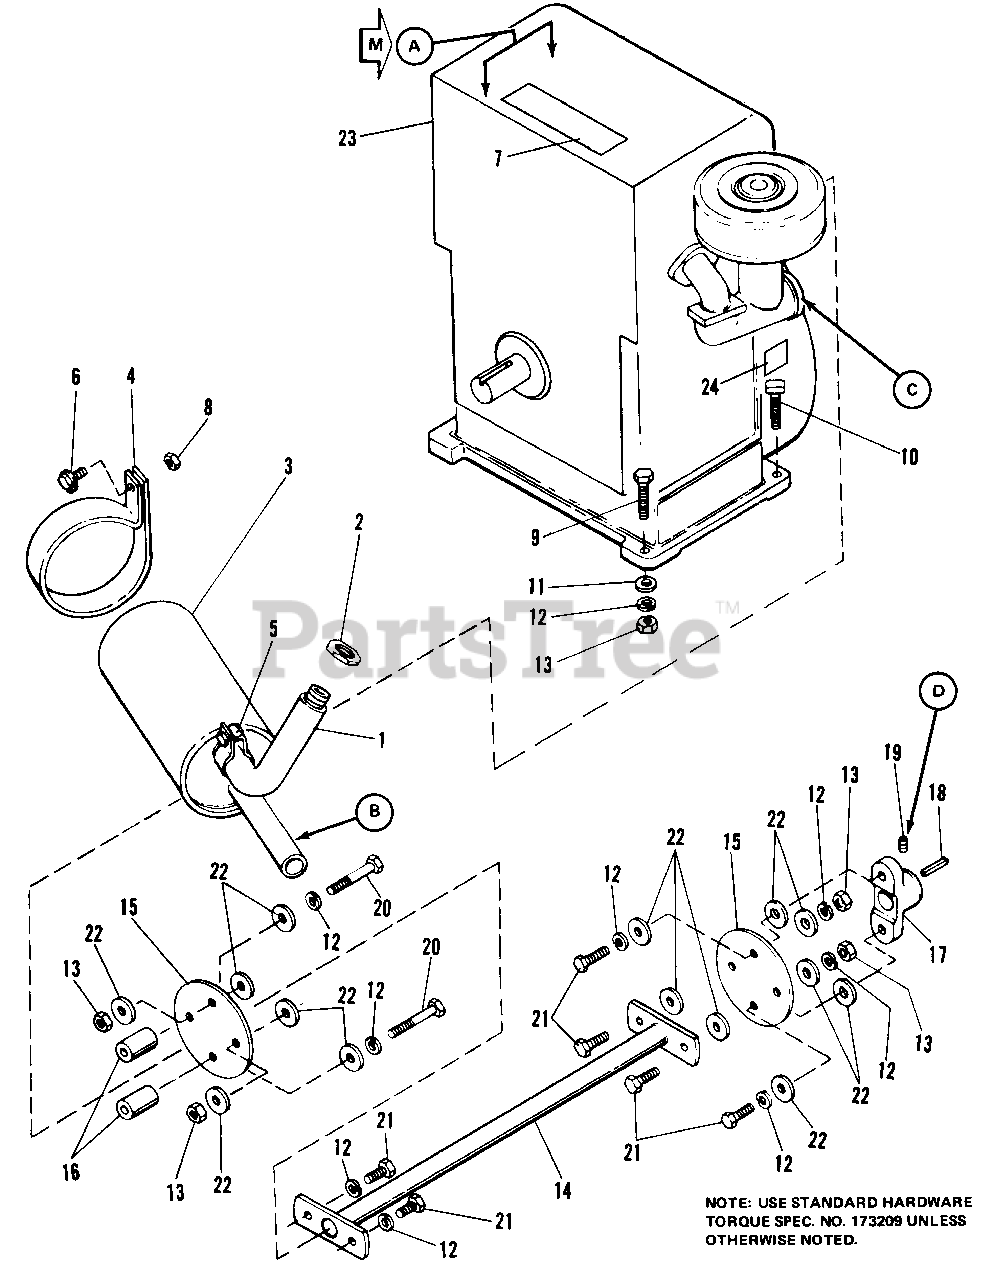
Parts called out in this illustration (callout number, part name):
1	ELBOW & NIPPLE ASSY
3	MUFFLER, Exhaust
4	STRAP, Muffler
5	CLAMP, Muffler
6	SCREW, Hex, Whizlock Flanqe, 5/16-18 x 1-1/2
7	DECAL, Caution
8	NUT, Hex, 5/16-18
9	CAPSCREW, Hex, Hd., 3/8-16 x 1-1/2
10	CAPSCREW, Hex Hd., 3/8-16 x 1-5/16
11	WASHER, 3/8
12	LOCKWASHER, 3/8
13	NUT, Hex, 3/8-16
14	SHAFT ASSY, Drive
17	FLANGE, Drive Shaft
18	KEY, Drive Shaft
19	SETSCREW, 3/8-24 x 3/8
20	CAPSCREW, Hex Hd., 3/8-16 x 2-1/4
21	CAPSCREW, Hex Hd., 3/8-16 x 1-1/4
22	WASHER, Special
23	ENGINE, 13 H.P., Briggs & Stratton
24	FILM, Oil Level Instructions
